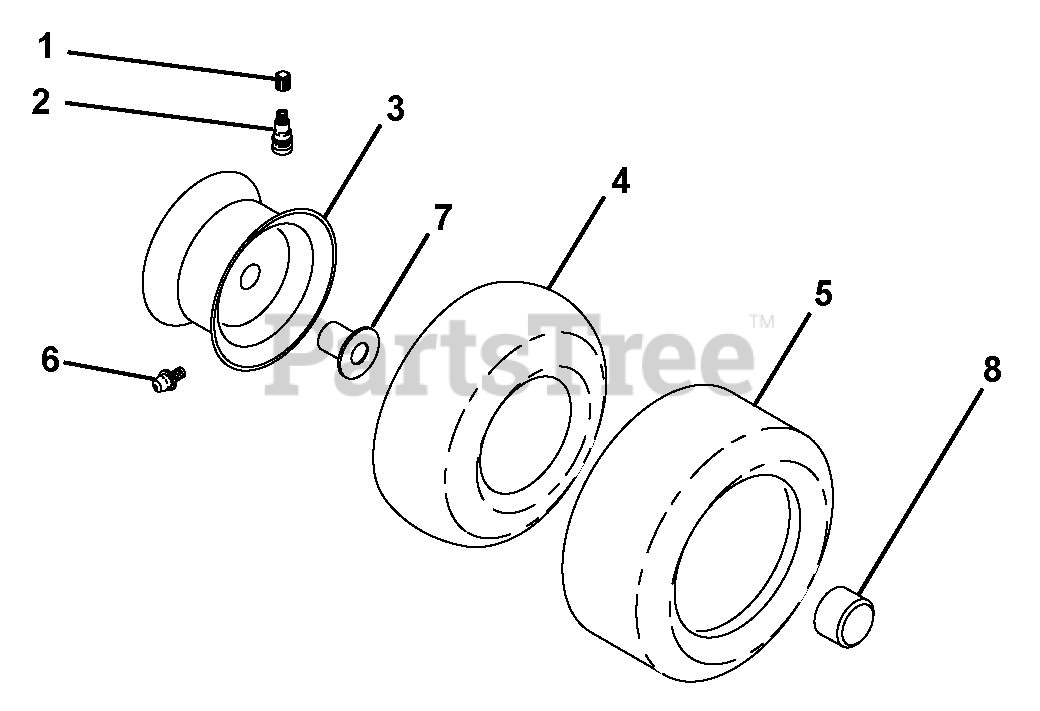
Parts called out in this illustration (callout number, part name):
2	VALVE STEM LT
3	RIM ASSEMBLY, FRONT
3	RIM.ASM.12X7.REAR.SILVER
4	TUBE.16X6.5/7.5-8
4	TUBE.23X9.5-12
5	TIRE HEAVY DUTY
6	ZERK FITTING M
7	BEARING T
8	CAP.HUB.FRONT.LT.BLACK
8	TIRE SEALANT
